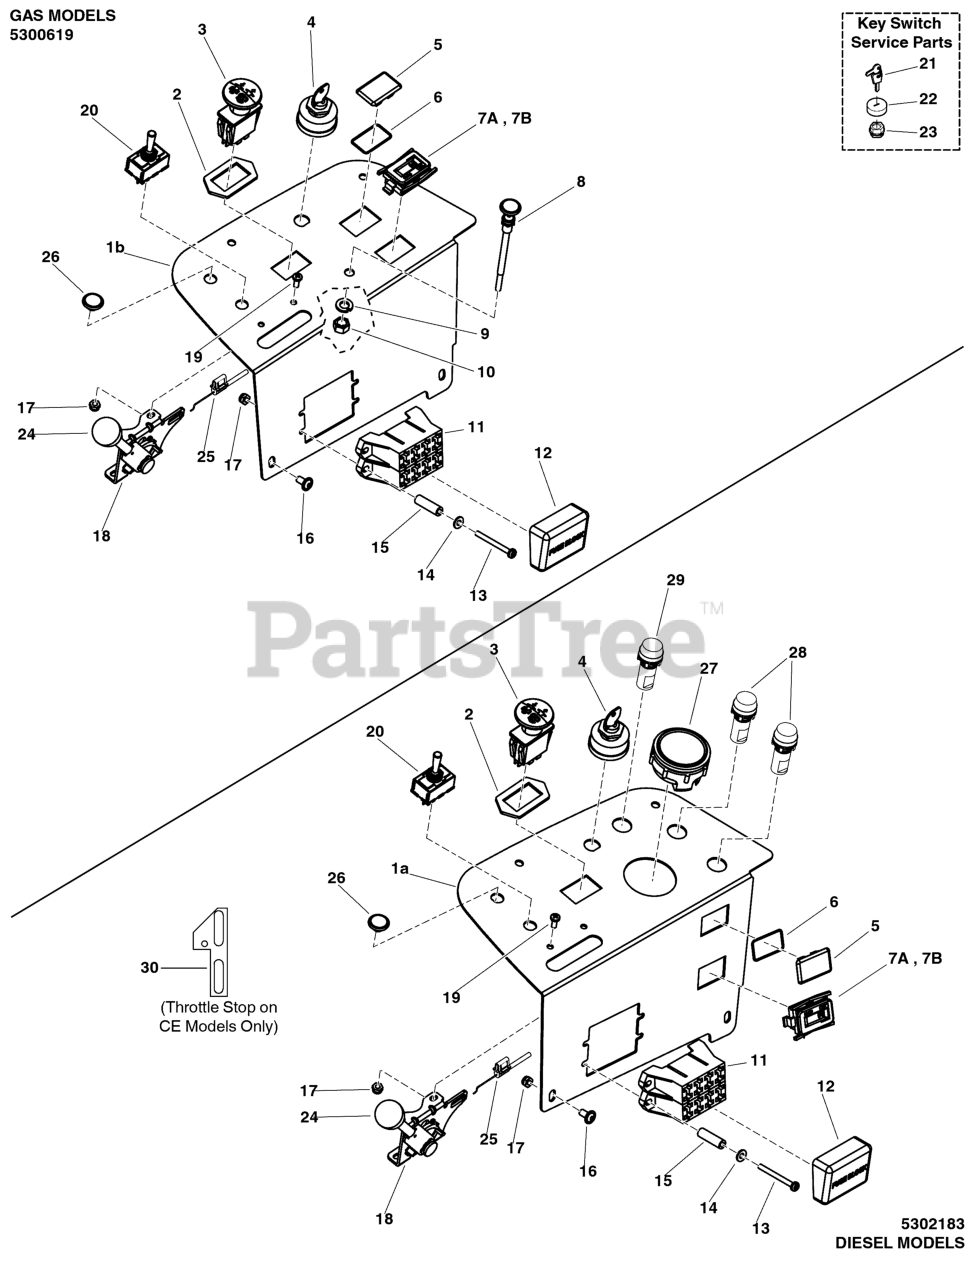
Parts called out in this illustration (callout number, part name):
1	DASH PANEL - BLACK
2	RING, SWITCH RETAINER
3	SWITCH, BLADE ENGAGEMENT
4	SWITCH, IGNITION, 25 AMP, 6 PO
5	PLUG, .820X1.44 HOLE, BLACK PLASTIC
6	O-RING, 7/8" ID X 1/16" W
7	HOUR METER, ASSEMBLE
7	HOUR METER
8	CABLE, CHOKE CONTROL, 39.5"
9	WASHER, 3/8" SPLIT LOCK
10	NUT, 3/8-24 HEX (SV)
11	FUSE, BLOCK (SV)
12	COVER, DOUBLE FUSE BLOCK
13	SCREW, #10-24 X 2" ROUND PHILLIPS
14	WASHER, #10 SAE
15	SPACER, .20 X .38 X 1.25
16	SCREW, ALLEN HEAD 1/4-20X.500 ZINC PHOS
17	NUT, Hex, Nylon Lock, #10-24
18	LEVER, THROTTLE CONTROL, HEAVY-DUTY
19	SCREW, #10-24 X 1/2" ROUND PHILLIPS
20	Switch, Electric Actuator
21	KEY, IGNITION MOLDED SET
22	COVER, PLASTIC, SNAP ON
23	PLASTIC NUT
24	THROTTLE CONTROL HANDLE/KNOB
25	CABLE, THROTTLE, 42"
25	CABLE, THROTTLE, 57.75"
26	PLUG, 1/2, BPF - 1/2
27	GAUGE, WATER TEMPERATURE
28	INDICATOR LAMP, RED, LED
29	YELLOW LED PILOT LIGHT
30	PLATE, THROTTLE STOP
